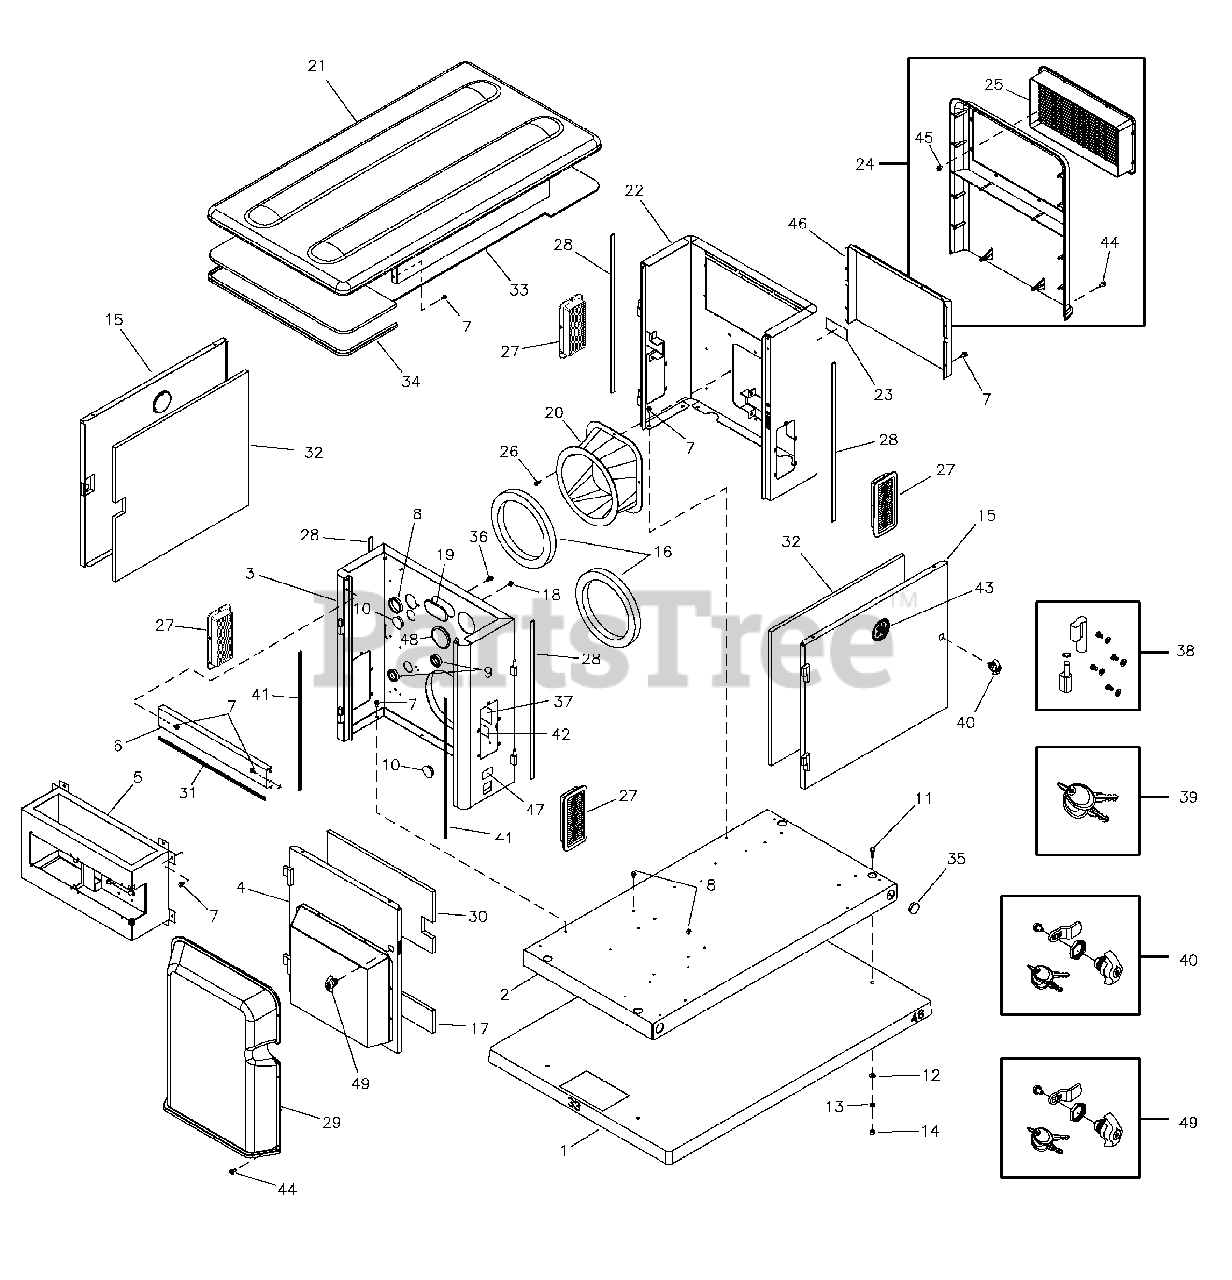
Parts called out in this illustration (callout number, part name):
3	BULKHEAD, Engine
4	DOOR
6	SUPPORT, Rail
7	BOLT
11	* CAPSCREW, Hex, Head, 3/8-16 x 1
12	* WASHER, Flat, 3/8 - M10
13	* WASHER, Lock, 3/8
14	* NUT, 3/8-16
15	DOOR
20	ADAPTER, Alternator
21	ROOF
22	BULKHEAD, Alternator
42	DECAL
44	SCREW
47	DECAL, Fuel Inlet
